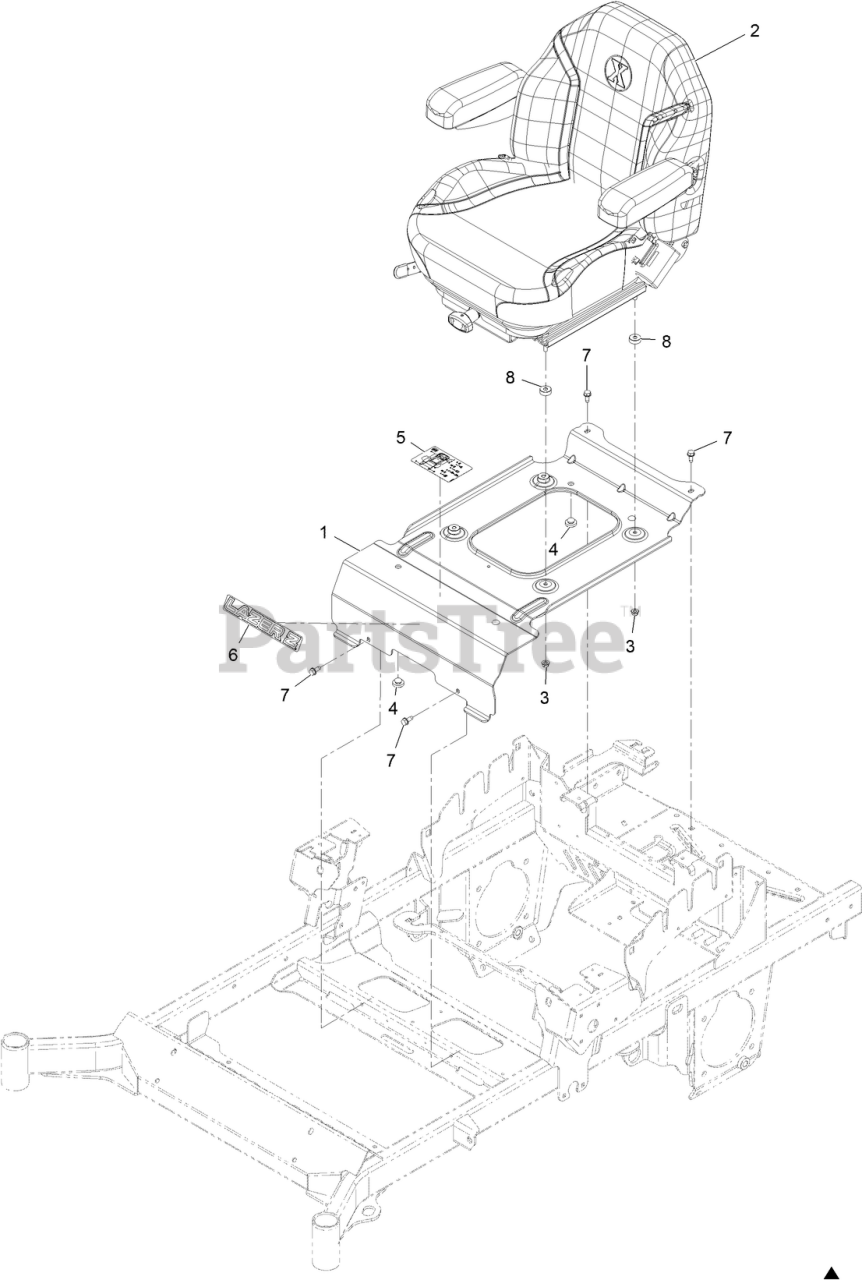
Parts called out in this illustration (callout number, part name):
1	Support, Seat
2	Seat, Suspension
3	NUT-HF, NI
4	BUMPER-SEAT
5	DECAL-SERVICE AID
6	DECAL, LAZER MODEL
7	SCREW-THD ROLL, HWH
